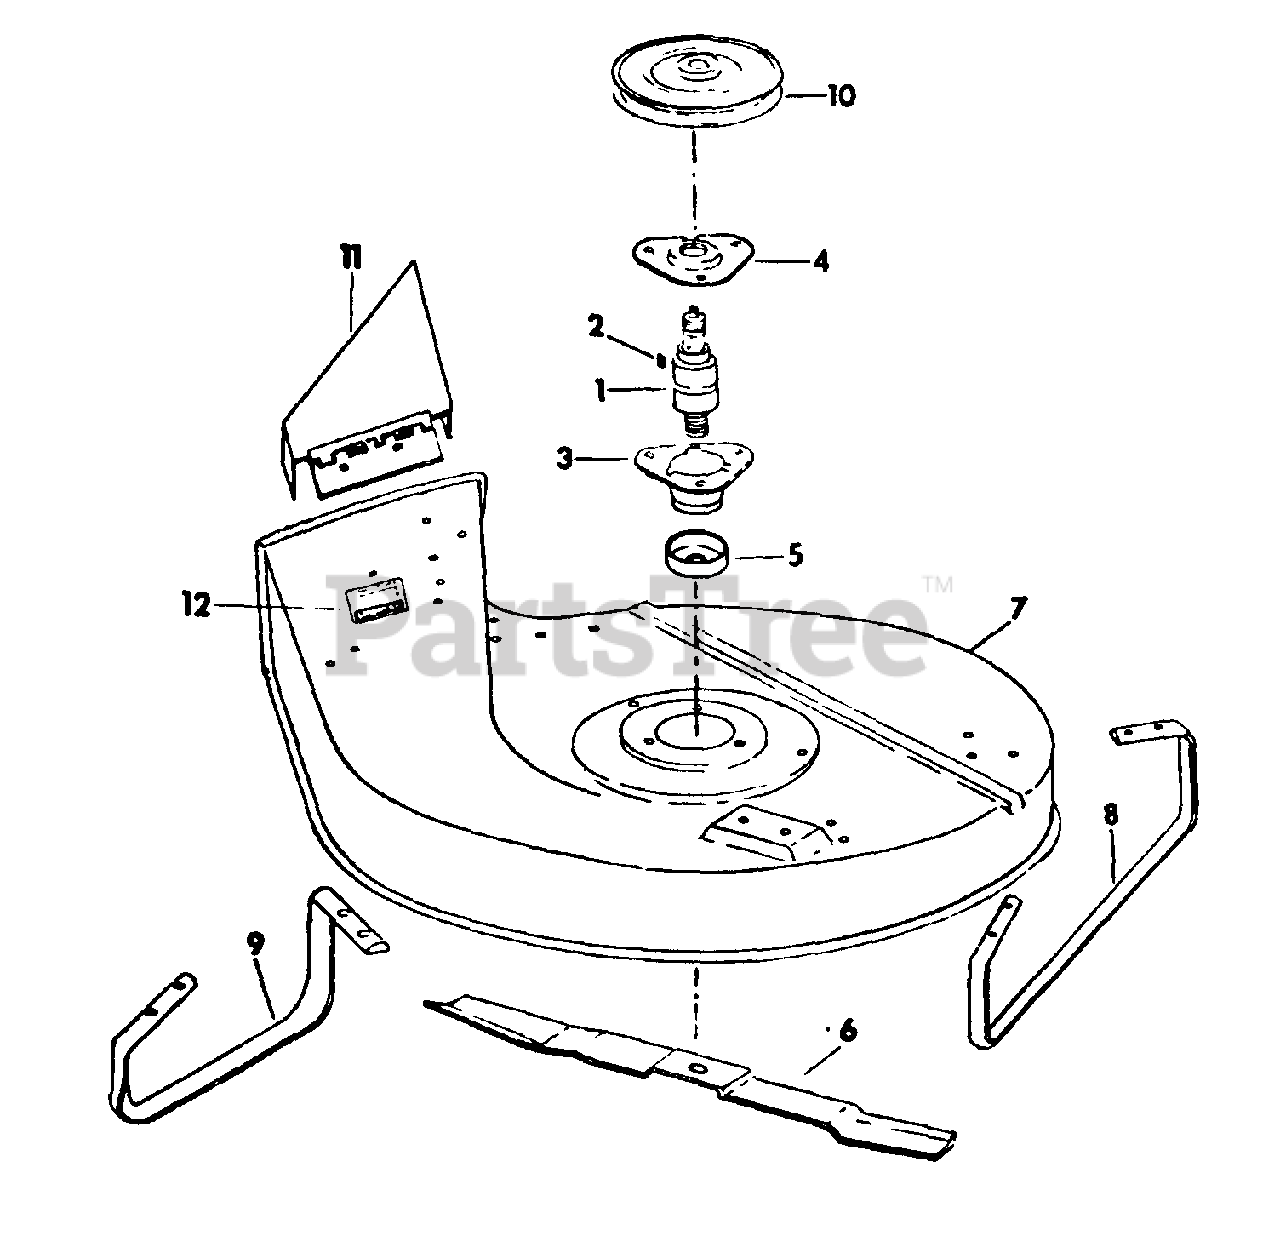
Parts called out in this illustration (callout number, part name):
1	BEARING, BALL AND FAN TYPE
2	KEY, 1/4 X 3/4 WOODRUFF 91
3	HOUSING, SPINDLE
4	CAP, SPINDLE HOUSING
5	CUP, SPINDLE
6	BLADE, 28 IN. MOWER
6	BLADE 28 IN. MOWER -COATED EDGE-
7	HOUSING, PRODUCT GRAPHIC, 57 801 C2, 28 IN. MOWER
8	RUNNER, LH MOWER
9	RUNNER, RH MOWER
10	PULLEY, CENTER
11	DEFLECTOR ASSY, 28 IN. MOWER
12	PRODUCT GRAPHIC, CAUTION
